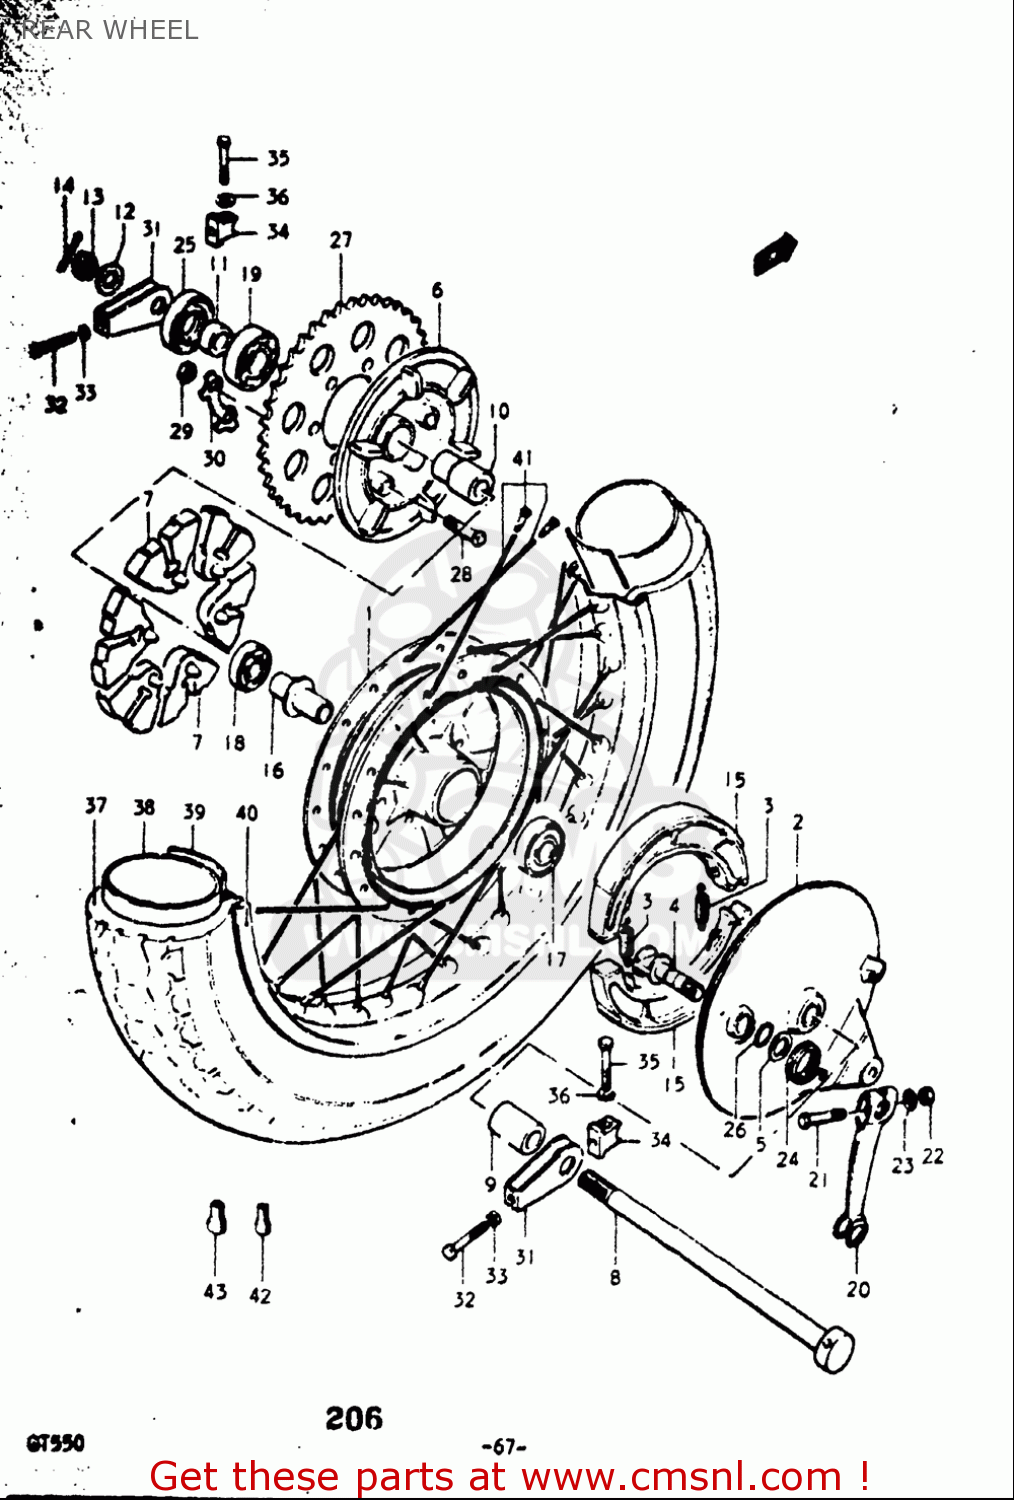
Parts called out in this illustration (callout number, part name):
3	SPRING,BRAKE SHOE
4	CAM,RR BRAKE
5	WASHER(15.5X24X1.6)
7	ABSORBER,RR HUB SHOCK
9	SPACER (17.5X28X51.8)
10	SPACER,REAR HUB BEARING
12	WASHER
13	NUT
14	PIN, COTTER
15	SHOE SET,BRAKE (NAS)
16	SPACER
17	BEARING
18	BEARING
19	BEARING(25X52X15)
21	BOLT
22	NUT
23	WASHER
24	SPRING
25	SEAL,OIL(30.5X52X8)
26	O RING(D:2.4,ID:14.8)
27	SPROCKET,RR
28	BOLT(10X45.5)
29	NUT
30	WASHER
31	ADJUSTER,CHAIN
32	BOLT(8X50)
33	NUT
34	SUPPORTER,CHAIN ADJUST
35	BOLT
36	WASHER
38	TUBE,INNER
39	PROTECTOR,INNER TUBE
40	RIM,WHEEL
41	SPOKE SET,REAR WHEEL
42	BALANCER,WHEEL (B)
43	BALANCER,WHEEL (30G)
